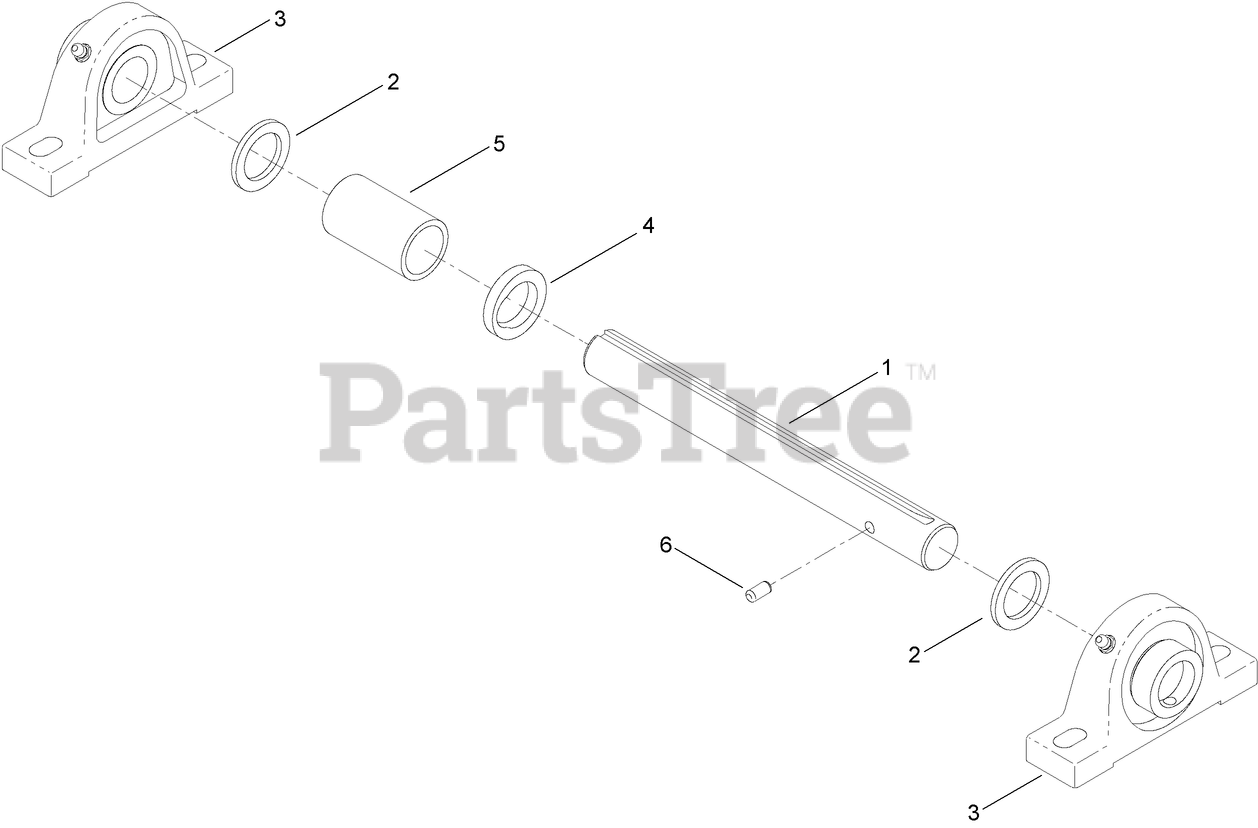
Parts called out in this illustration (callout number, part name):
1	SHAFT-PINION
2	WASHER-THRUST
3	BEARING-BLOCK, PILLOW
4	WASHER
5	SPACER-IDLER
6	PIN-DOWEL
